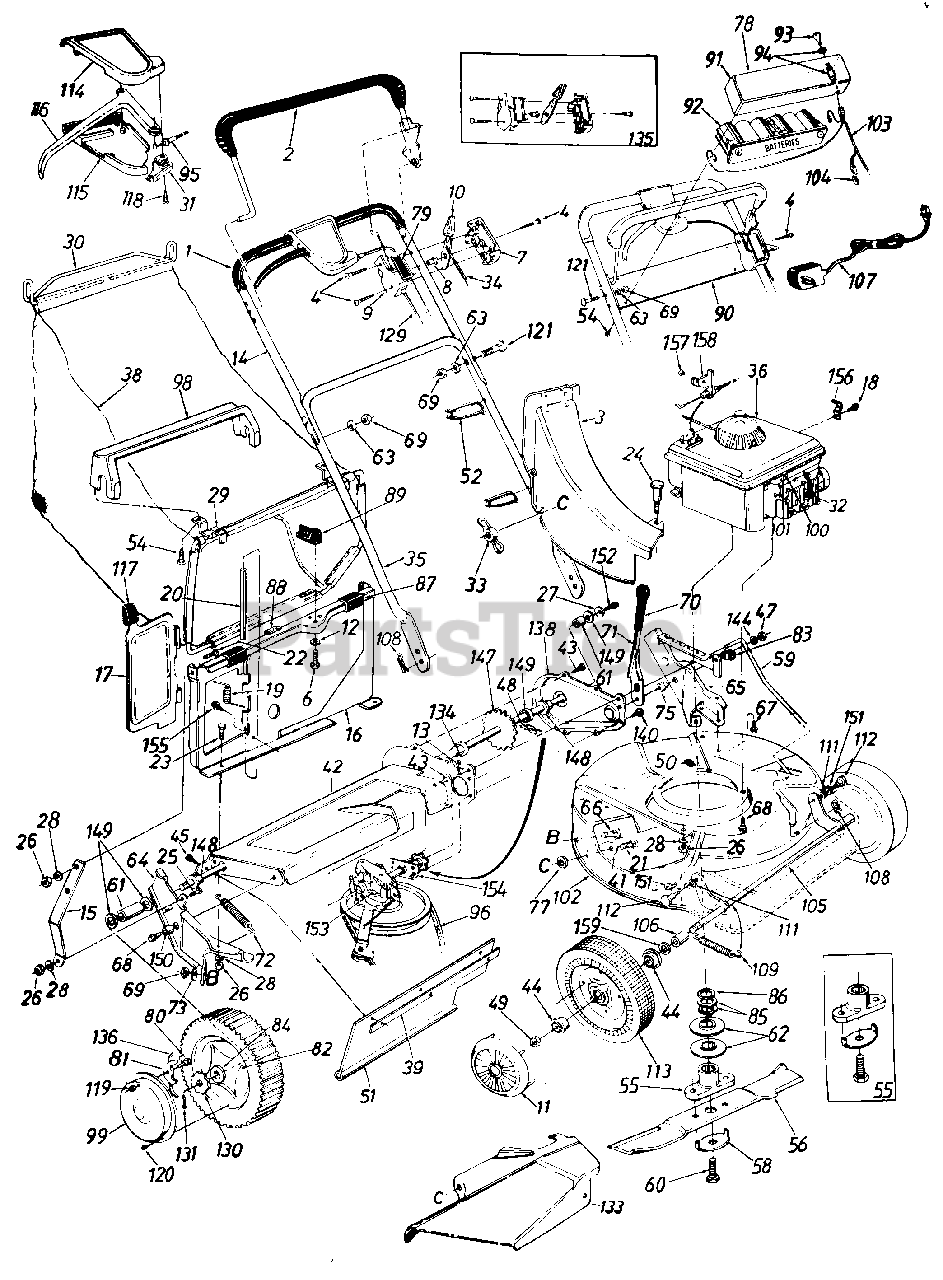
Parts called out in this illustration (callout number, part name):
1	Foam Grip
2	Control Handle Ass'y.-L.H.
3	Top Discharge Chute Ass'y.
4	Truss Mach. Scr. #12 x 1.50" Lg.
6	Hex Wash. TT-Tap Scr. 1/4-20 x .75" Lg.
7	Control Panel Half
8	Control Disc Pin
9	Clutch Panel Half
10	Throttle Control Lever
11	Hub Cap
12	Spring Wash. .32" I.D.
13	Cotter Pin 8/32" Dia. x .75"
14	Upper Handle-Painted
15	Panel Support Brkt.
16	Top Catcher Panel Ass'y.
17	Top Discharge Door
18	Hex B-Tap Scr. #10 x .38"
19	Torsion Spring
20	Pivot Pin
21	Carriage Bolt 1/4-20 x .62"
22	Truss Mach. Scr. 1/4-20 x 3/4" Lg
23	Hex Bolt 1/4-20 x .50" Lg.
24	Shoulder Bolt .312 Dia. x .18 Lg.-Special
25	Hex Bolt 1/4-20 x .62" Lg.
26	Hex Nut 1/4-20 Thd.
27	Bell-Wash. 1/4" I.D.
28	L-Wash. 1/4" I.D.
29	Front Grass Catcher Frame
30	Grass Catcher Handle
31	S.P. Control Cover
32	Spark Plug Insulator
33	Wing Nut w/Washer
34	Throttle Control Wire 58"
35	Lower Handle-Painted
36	Engine
38	21" Top Discharge Grass Bag-Black
39	Retaining Strip
41	Fl-Wash. .344" I.D. x .62"
44	Flange Ball Bearing 1/2" I.D.
45	Hex AB-Tap Scr. 1/4 x .62"
47	Hex Patch L-Nut 3/8-24 Thd.
48	#48 Chain .500" Pitch x 30 Links
49	Hex L-Nut 1/2-20 Thd.
51	Rear Flap 3.75" x 17.30" Lg.
52	Cable Tie
54	Hex AB-Tap Scr. 1.0" Lg.
55	Blade Adapter Kit
56	21" Blade
58	Blade Bell-Wash. .44" I.D. x 2.38"
59	Height Adj. Rod 19.42" Lg.
60	Hex Bolt 7/16-20 x 1.5" Lg. (Grade 5)
61	Spacer .513" I.D. x .703" O.D. x .69" Lg.
62	Serrated Pulley Half
63	L-Wash. 5/16" I.D.*
64	R.H. Handle Wheel Brkt. Ass'y.
65	L.H. Handle Wheel Brkt. Ass'y.
66	Carriage Bolt 5/16-18 x .62"
67	Hex Wash. Hd. B-Tap Scr. 5/1 6-1 8
68	Hex Wash. Hd. TT-Tap Scr. 3/8-1 6
69	Hex Nut 5/16-18 Thd.
71	Height Adj. Lever
72	Extension Spring .50" O.D. x 3.80" Lg.
73	Bell-Wash. 5/16" I.D.
75	Shld. Spacer .500" Dia.
77	Bolt Retainer 1/4 x .50" O.D.
78	Instruction Label
79	Control Label
80	Shld. Scr. .342" Dia. x .268
81	Pawl
82	Wheel Ass'y. Comp.
83	Clamp
84	Bearing 1/2" I.D.
85	Wave Washer 1.005" I.D.
86	Serrated Washer 1.0" I.D.
87	Panel Clip
88	Foam Strip 1" Lg.
89	Grass Catcher Locking Knob
90	Lower Battery Tray
91	Upper Battery Tray
92	12 Volt Battery
93	Key
94	Key Switch
95	S.P. Cable x 50" Lg.
96	"V"-Belt
98	Bag Handle (Black)
99	Rear Hub Cap
100	Hex B-Tap Scr. #10 x .62"
101	Cable Clamp
104	Plug
105	Front Axle Ass'y.
106	Sleeve .526" I.D. x .690" O.D. x .880" Lg.
107	Battery Charger
108	Intern. Cotter Pin 5/16" Dia.
109	Extension Spring .60" O.D. x 3.20" Lg.
111	Intern. L-Wash. 3/8 I.D.
112	Shld. Bolt .575" Dia. x .42
113	"T" Tread (7 x 1.75")
113	Wheel Ass'y. Comp.
114	Self-Propelled Control Cover
115	Self-Propelled Control Cover
116	Control Lever
117	Door Grip
118	Fl-"C"-Sunk Hd. Tap Scr. #10 x .75" Lg.
119	Hex Ins. L-Nut 1/4-20 Thd.
120	Pan Hd. Tap Scr. #12 x .5" Lg.
121	Curved Carr. Bolt 5/16-18 x 1.38n Lg.
129	Control Cable 46" Lg.
130	Ratchet Wheel 1.62" O.D.
131	Cotter Pin 1/8" Dia. x 1.00" Lg.
133	Side Chute Deflector Ass'y.
134	Hex Flange Bearing
135	Kit-Control Housing Comp.
136	Spring-Nylon
144	Fl-Wash. .385" I.D. x .87"
147	Rear Shaft Ass'y. 21.94" Lg.
148	Hex Flange Bearing .506" I.D. Plastic
149	Fl-Wash. .531" I.D. x .930"
150	Spacer .383" I.D. x .503 O.D.
151	Flanged Nyliner Brg.
152	Hex Bolt 1/4-20 x .62" Lg. (Grade 5)
153	Transmission Comp.
154	Hex Bearing Cup
155	Hex B-Tap Scr. #10 x .38
156	Cable Clamp
157	Pop Rivet .156" Dia.
158	Cable Bracket
159	Fl-Wash. .51" I.D. x .75" O.D.
